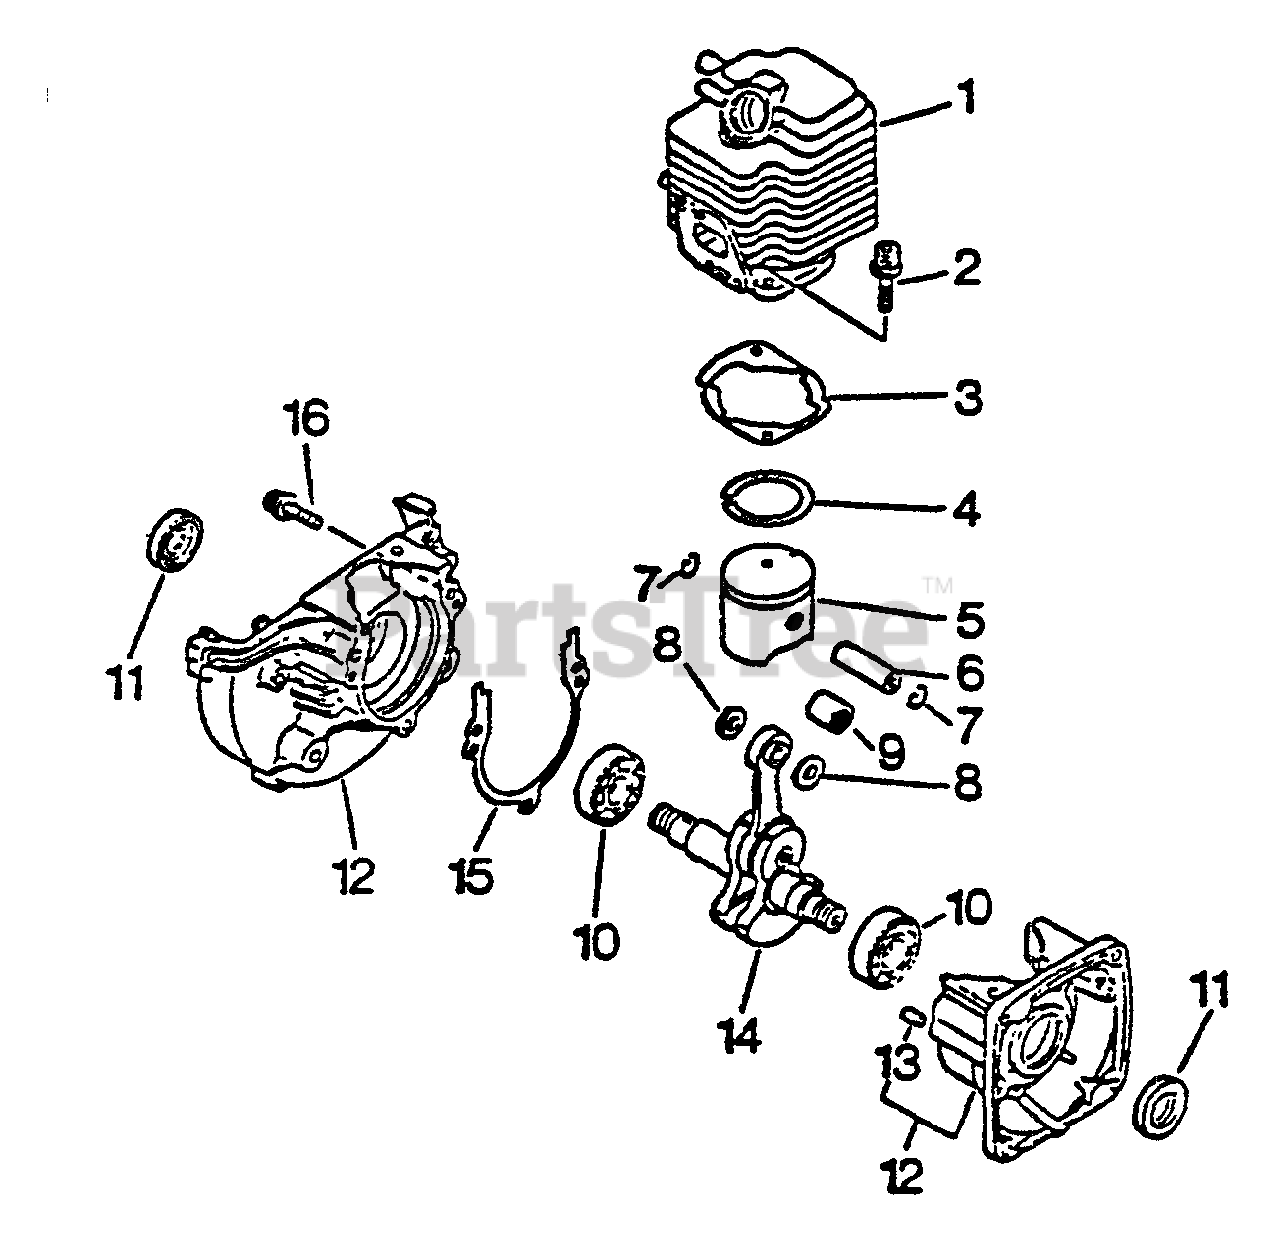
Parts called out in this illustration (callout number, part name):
1	CYLINDER
2	SCREW - 5X22
3	GASKET, CYLINDER
4	RING, PISTON
5	PISTON
6	PIN, PISTON
7	RING, RETAINING
8	SPACER, PISTON
9	BEARING, NEEDLE
10	BEARING, BALL - 6201
11	SEAL, OIL
12	CRANKCASE KIT
13	PIN - LOCATING
14	CRANKSHAFT ASSY
15	GASKET, CRANKCASE
16	SCREW - 5X28
